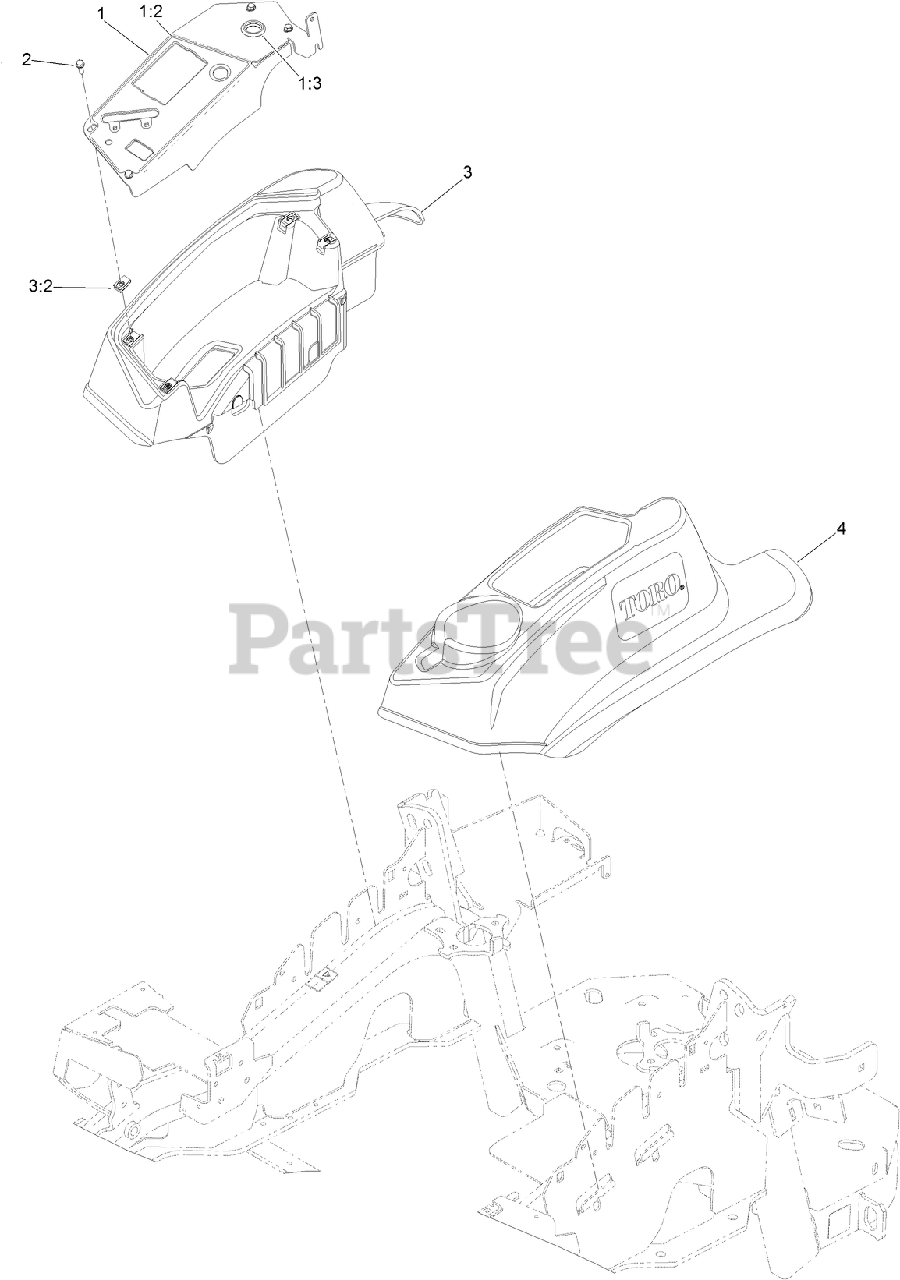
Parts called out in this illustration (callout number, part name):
1	CONTROL PANEL ASM
1:2	DECAL-PANEL, CONTROL
1:3	PLUG-PLASTIC
2	SCREW-HWH
3	RH CONSOLE ASM
4	CONSOLE-LH
